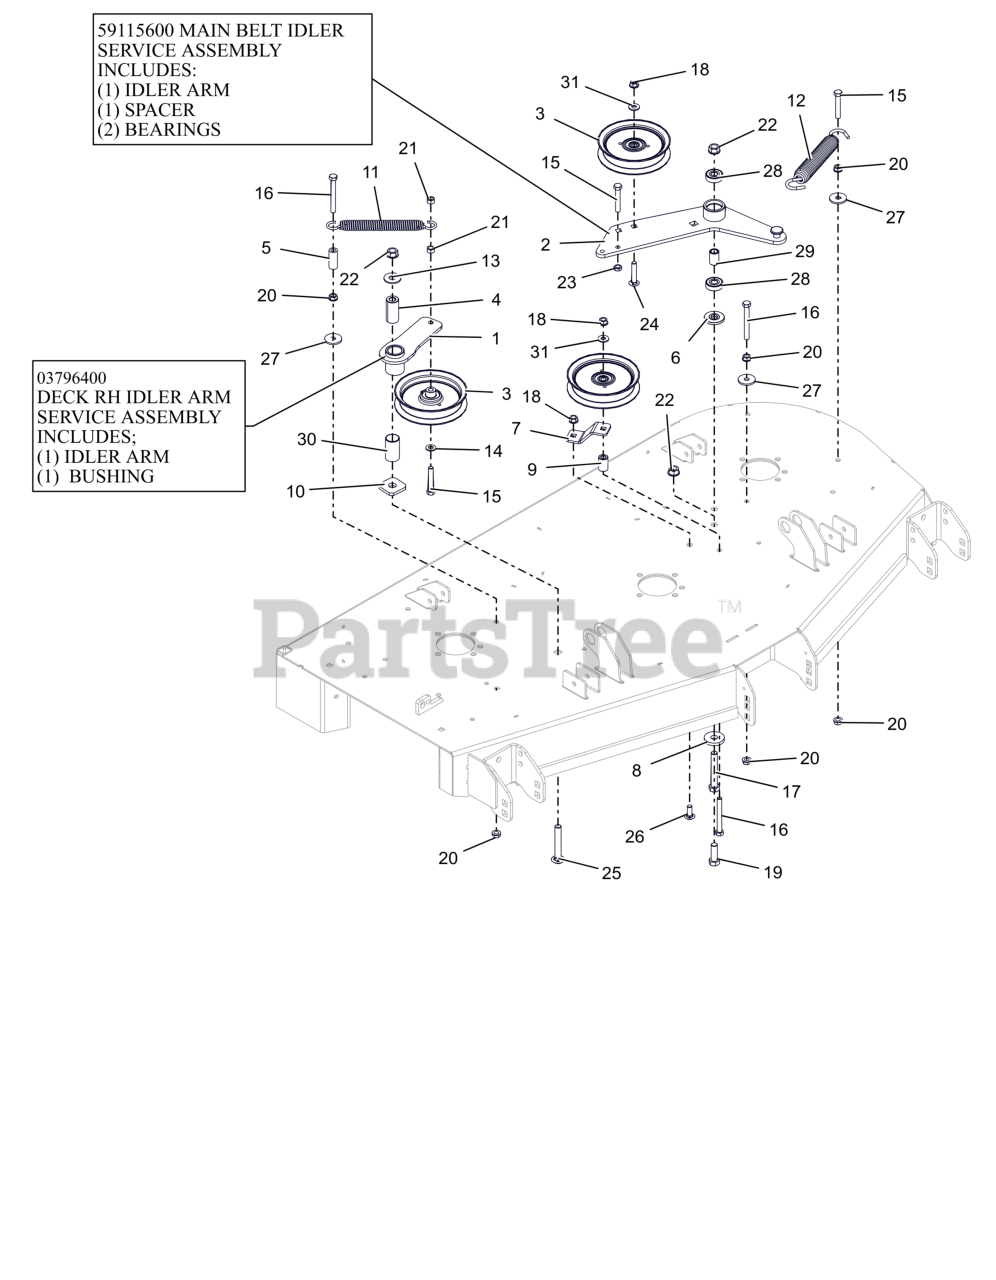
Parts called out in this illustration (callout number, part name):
1	WMT, IDLER ARM - BLACK
1	ASM, IDLER ARM (DECK)
2	WLDMT, DECK PTO IDLR ARM
2	ASSEMBLY, MAIN BELT IDLER
3	IDLER, FLAT 5.00"
4	BSHG, SPCR .502X.997X2.03 PM
5	HOSE, .38 X 1.65
6	SPACER, IDLER ARM
7	PTO FIXED IDLER MTG BRKT-ORG
8	WSHR-FL-STL 0.557X1.625X0.25 ZCC
9	BUSHING, SLV .380X.750X1.190
10	WSHR-FLT .640X1.75X.250
11	SPRING, EXTENSION
12	SPRING, EXTENSION
13	WSHR,FLT .563X1.375X.109 ZCC
14	WSHR,FLT .406X.812X.065 ZCC
15	BLT,HEX .38-16X2.25 G5 ZCC
16	BLT, HEX .38-16X3.25 G5 ZCC
17	BLT,HEX .50-13X3.25 G5 ZCC
18	NUT-LK-CTR-FLG .375-16 GF ZCC
19	BLT,HEX .50-13X1.50 G5 ZCC
20	NUT, SPNLK-FLG .38-16 G5 ZCC
21	NUT-LK-CTR .38-16 ZC120
22	NUT-LK-CTR-FLG .500-13 GG ZCC
23	NUT-JAM .375-16 G2 ZCC
24	BLT,RHSSN.375-16X2.00 G5 ZCC
25	BTL,RHSSN .500-13 X 3.25 G5 ZCC
26	BLT,RHSSN .38-16X1.00 G5 ZCC
27	WSHR,FLT .406X1.375X.135 ZCC
28	BRG-BALL .500X1.38X.437
29	SPACER .510 X .75 X 1.1485
30	BSHG, 1.00X1.125X1.937
31	WSHR,FLT .375X.875X.083 ZCC
